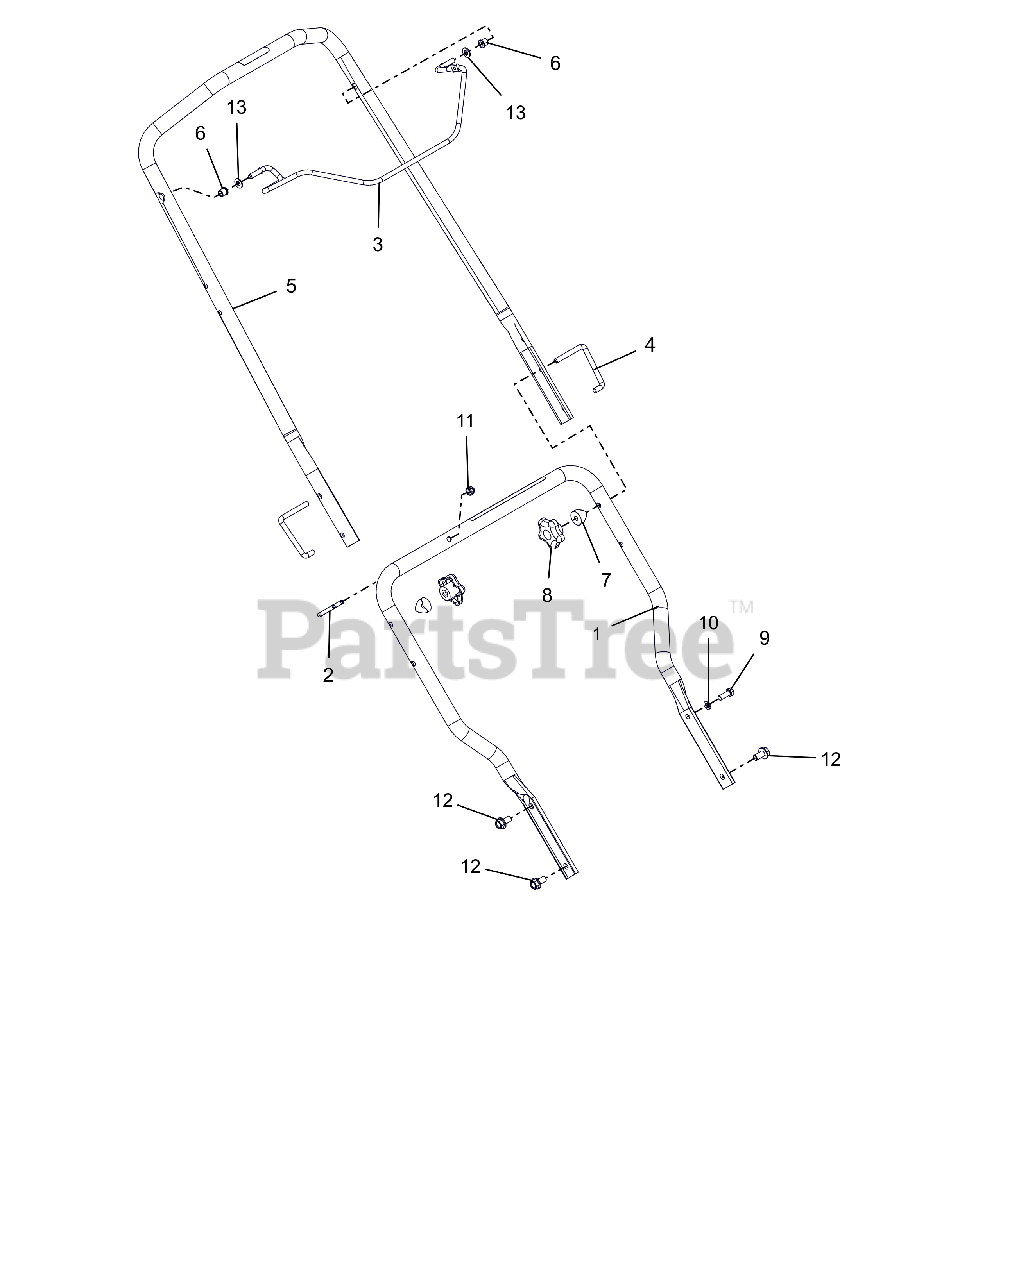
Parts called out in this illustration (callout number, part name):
1	HANDLEBAR, LOWER W/DECAL
2	GUIDE, PULL CORD
3	BAIL, AUGER
4	PIVOT, BOLT, HANDLEBAR
5	HANDLEBAR, UPPER W/DECAL
6	BSHG-FLG .325X.444X.440X.560
7	SPACER, HANDLEBAR
8	KNOB, STAR, 5/16-18UNC
9	BLT-HEX .31-24X.875 GR5YZ EP80
10	@WSHR-LK .31X.078 REG YWZC
11	@NUT-LK-TOP-FLG .25-20 YWZC
12	BLT-SERHFWH .38-16X.75 YWZC
13	@WSHR-FL-STL.344X.688X.065YWZC
